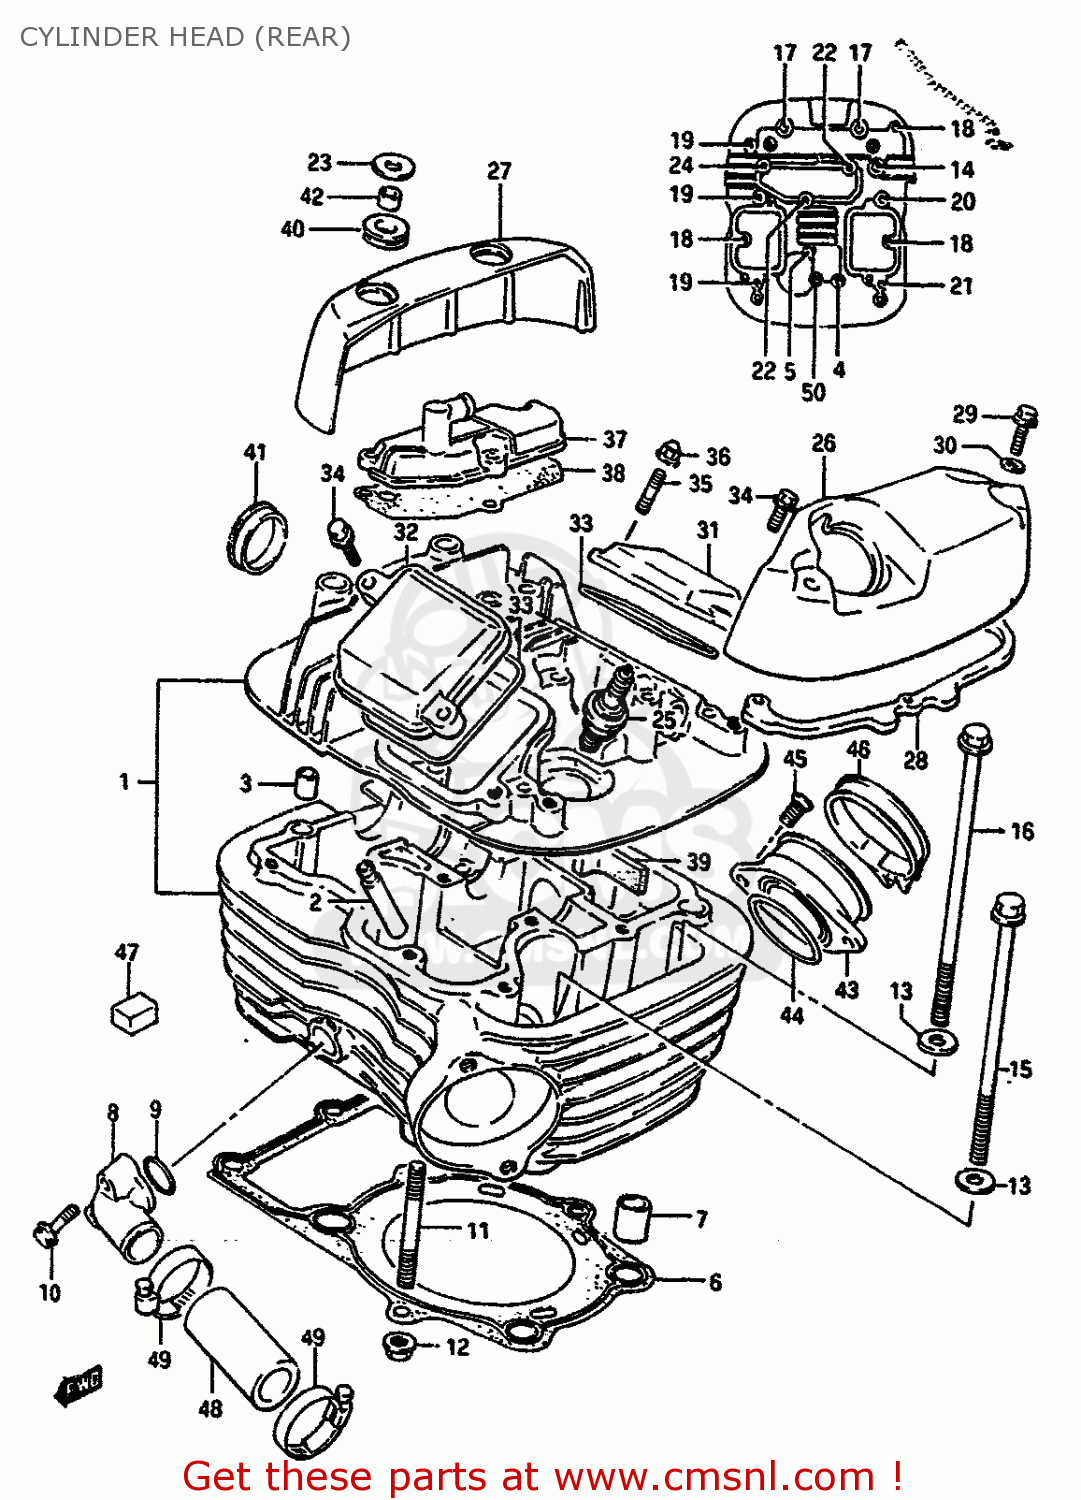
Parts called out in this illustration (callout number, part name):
1	HEAD ASSEMBLY,CYLINDER,REAR
2	GUIDE,VALVE
3	PIN(11X14)
4	BOLT(6X50)
5	BOLT(6X55)
6	GASKET,CYLINDER HEAD RR (MCA)
7	PIN
8	UNION,CYLINDER HEAD WATER
9	O RING(D:2.4,ID:17.8)
10	BOLT
11	BOLT,STUD
12	NUT
13	WASHER(10.5X22X2.3)
14	BOLT(8X140)
15	BOLT(10X155)
16	BOLT(10X165)
17	BOLT(8X245)
18	BOLT 6X25
19	BOLT
20	BOLT
21	BOLT
22	BOLT(6X55)
23	WASHER (8.2X24X1.6)
24	BOLT 6X20
25	PLUG,SPARK(DPR8EA-9)
26	CAP,CYLINDER HEAD COVER RR,L
27	CAP,CYLINDER HEAD COVER RR,R
28	CUSHION,RR,L CAP
29	BOLT
30	WASHER
31	CAP,INSPECTION
32	CAP,INSPECTION,EXHAUST
33	GASKET,INSPECTION CAP (NAS)
34	BOLT
35	STUD 6X16
36	NUT
37	COVER,BREATHER
38	GASKET,BREATHER COVER (NAS)
39	PLATE,HEAD COVER RR
40	CUSHION
41	PLUG
42	BUSH
43	PIPE,INTAKE
44	O-RING (D:2.4 ID:39.7)
45	SCREW
46	CLAMP,PIPE
47	PAD
48	HOSE,CYLINDER HEAD JOINT
49	CLAMP
50	BOLT
